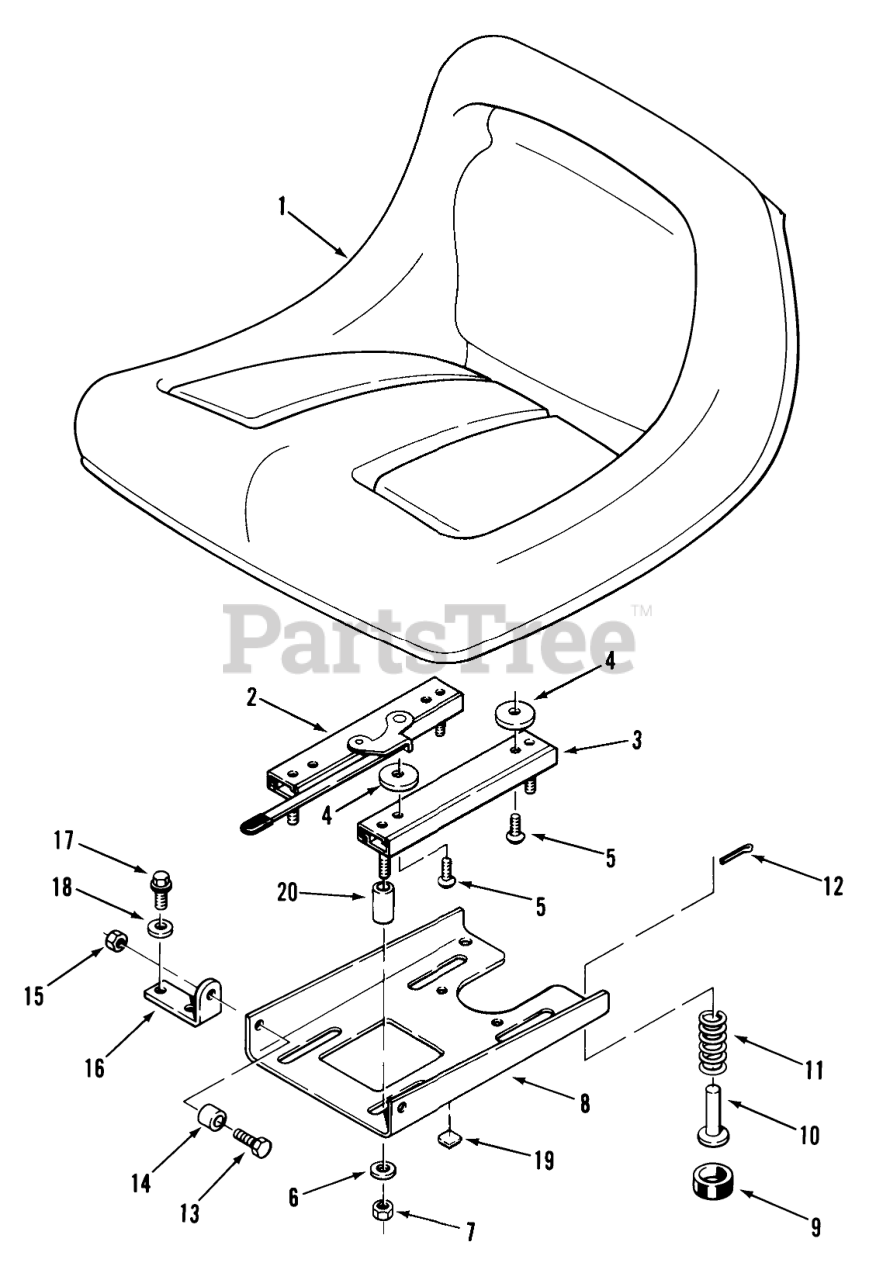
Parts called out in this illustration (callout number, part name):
1	Seat
2	ADJUSTER-SEAT RH
3	ADJUSTER-SEAT LH
4	SPACER-NYLON
5	Screw 5/16-18 x 3/4 Black
6	Collar
7	Nut
8	Pivot Plate
11	SPRING
12	Cotter Pin
13	HHCS
14	BUSHING
15	Nut
16	BRACKET-PIVOT
17	SEAT BOLT FOR C195
18	WASHER 5/16 SAE
19	BUMPER
20	Spacer
